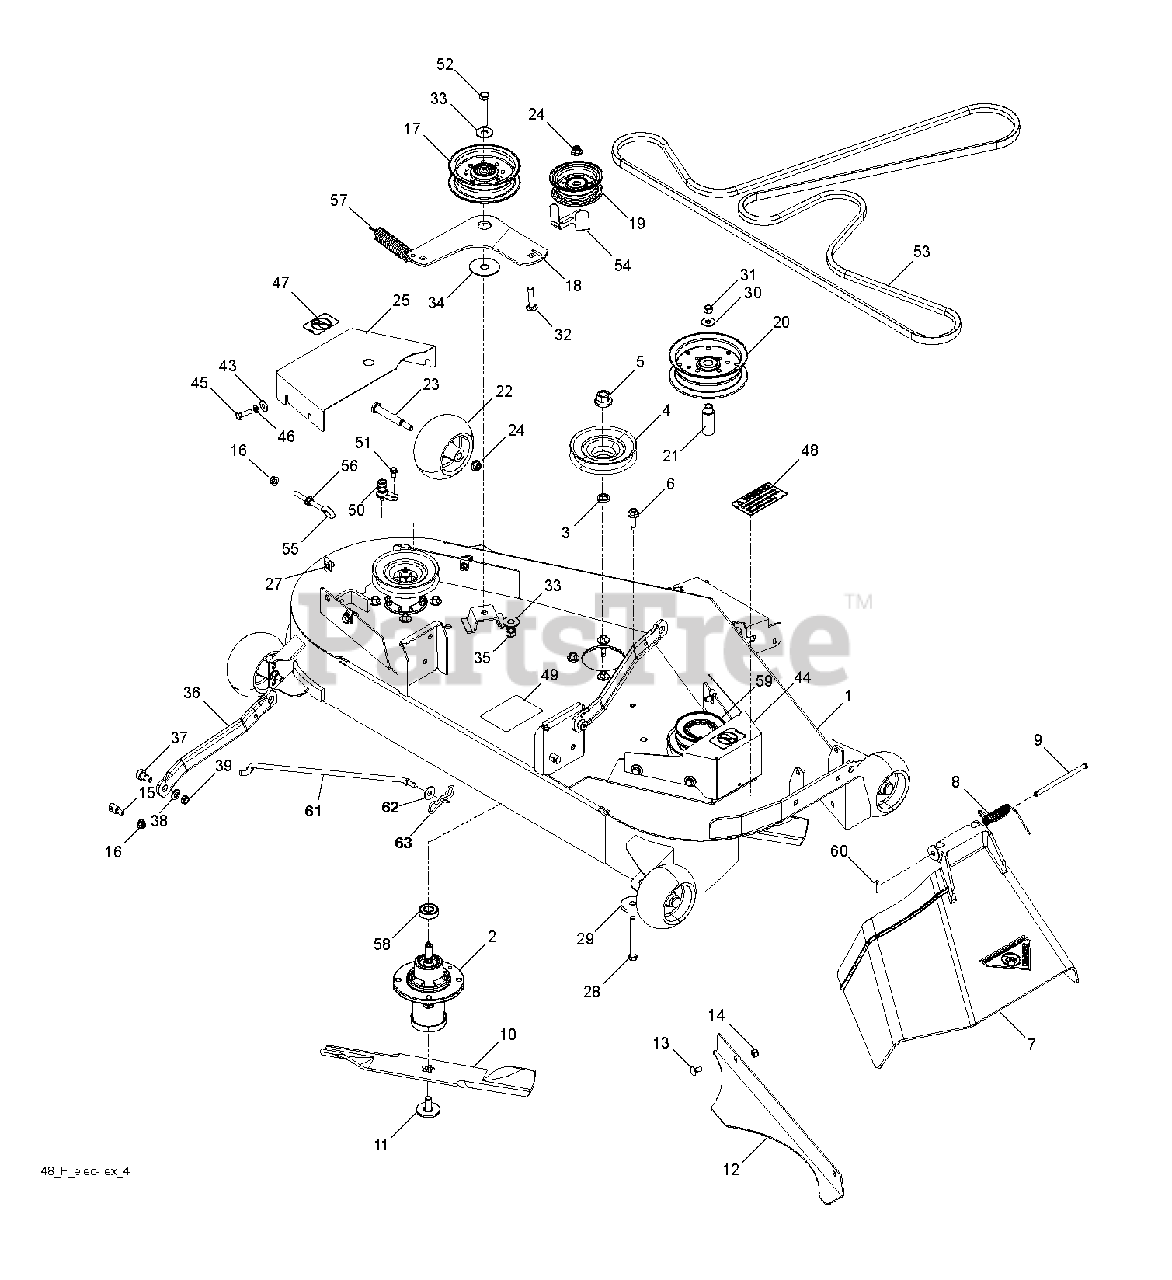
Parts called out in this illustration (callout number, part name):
1	DECK SVC W/DECALS.48.YTH/GTH.O
2	MANDREL.DECK.ASSEMBLY
3	WASHER-SPACER
4	PULLEY.DRIVEN.DECK.48'
5	LOCKNUT - 9/16
6	WASHER HEAD SCREW
7	DISCHARGE CHUTE, 48"
8	SPRING - TORSION
9	PIN, CLEVIS 5/16 X 5.19
10	BLADE, 16-1/4"
11	BLADE BOLT ASSY-7/16" TB REPL
12	CONFINEMENT PLATE 48" BLK
13	CARRIAGE BOLT 5/16C X 5/8"
14	NUT 5/16 NYLOC
15	STUD.FASTNER.W/ANTI-ROTATE
16	5/16-18 NYLOC FLANGE NUT
17	PULLEY.IDLER.MWR.STATI.LH
18	ARM, IDLER, BLK
19	PULLEY.IDLER.FLAT
20	PULLEY, IDLER
21	BUSHING, IDLER
22	GAUGE WHEEL
23	SHOULDER BOLT 1/2X2-5/8 ZD SPE
24	NUT 3/8-16 HEX FLG NYLOC ZD
25	SHIELD.BELT.LH.ORANGE
27	U-CLIP 5/16-18 NUT RETAINER
28	HCS 3/8-16 X 3-1/2 GR5 ZD
29	SPINDLE WASHER
30	RP WASHER 3/8 FLAT
31	NUT 3/8-16 NYLOC
32	RHSNB 3/8-16X1-3/4
33	WASHER 7/16 FLAT ZD
35	7/16-14 HEX NUT W/NYL RING ZD
36	ARM.SUSPENSION.MOWER
37	SB 3/8-16 X 3/8 SKT HD ZD
38	WASHER 3/8 SAE FLAT
39	NUT HEX 3/8-16 NYLON, THIN
43	WASHER 5/16 FLAT
44	SHIELD, BELT, RH 48 ORG
45	HCS 5/16C X 1
46	WASHER 5/16 LOCK
47	DECAL, NO STEP
48	DECAL, CAUTION
49	DECAL.MOWER.SCH.48/54
50	PORT.WASHOUT
51	BOLT 1/4-20 X 1/2 HWST
52	BOLT 7/16-14 X 2-1/2 GR 5 ZD
53	BELT, 135" EL
54	BELT GAURD
55	EYE BOLT 5/16 X 3.50
56	NUT 5/16C WHIZ
58	BEARING, BALL
59	RP PULLEY, COLLECTION 48
60	RETAINER CLIP
61	ROD.ANTI.SWAY.48/54"K4
62	WASHER
63	PIN.COTTER.5/16.BOW TI
